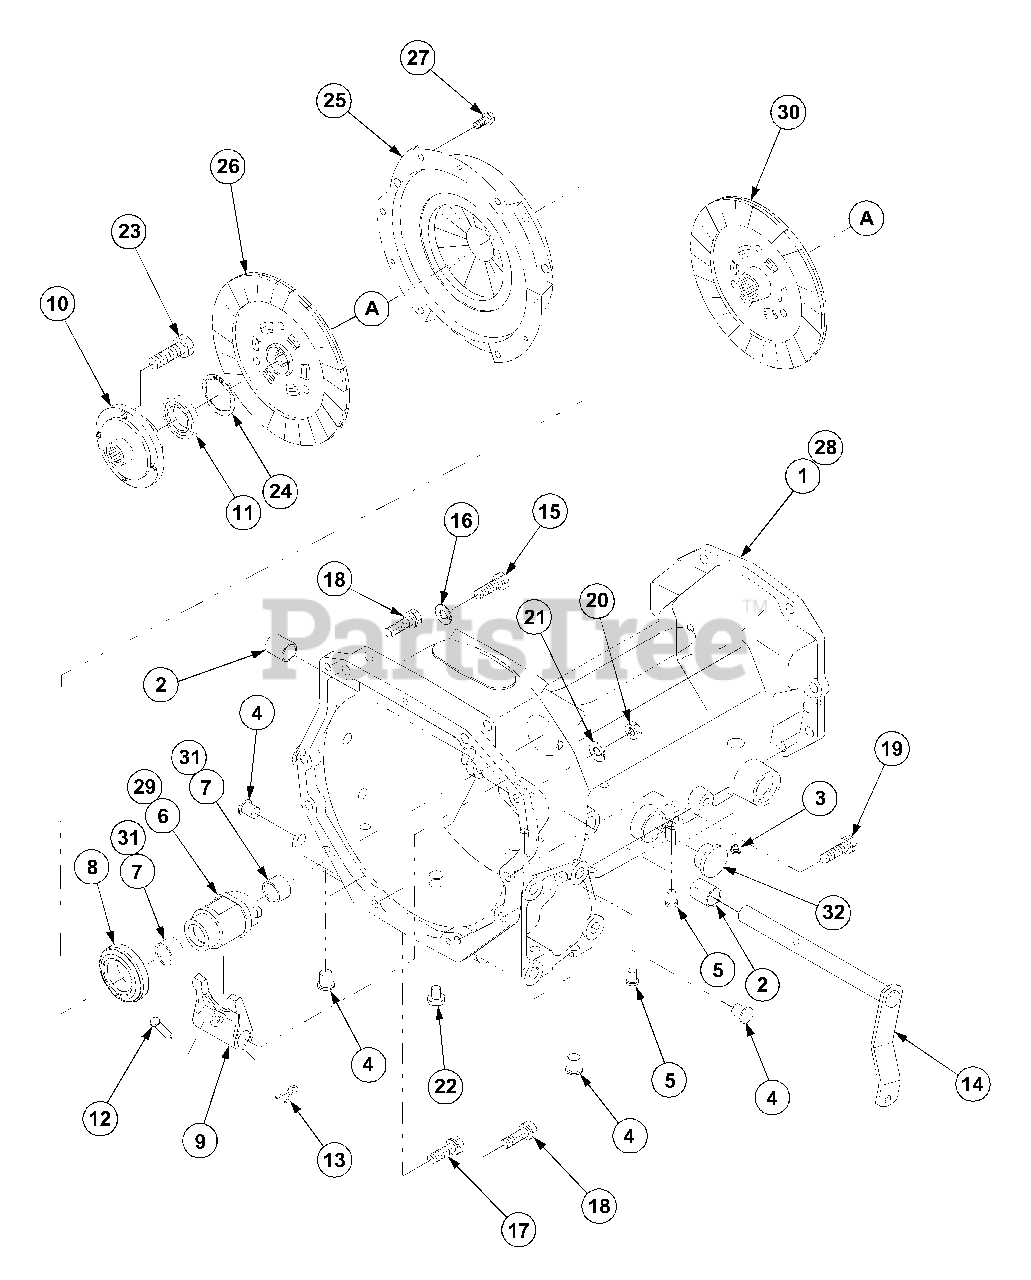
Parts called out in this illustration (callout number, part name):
1	Housing,Clutch
7	Bushing
14	Shaft,Release
16	Washer,Spring
17	Bolt,w/Washer
18	Bolt,w/Washer
19	Bolt,w/Washer
21	Washer,Spring
27	Bolt,w/Washer
28	Housing,Clutch
29	Hub,Release
30	Disk,Clutch
32	Seal Cap
